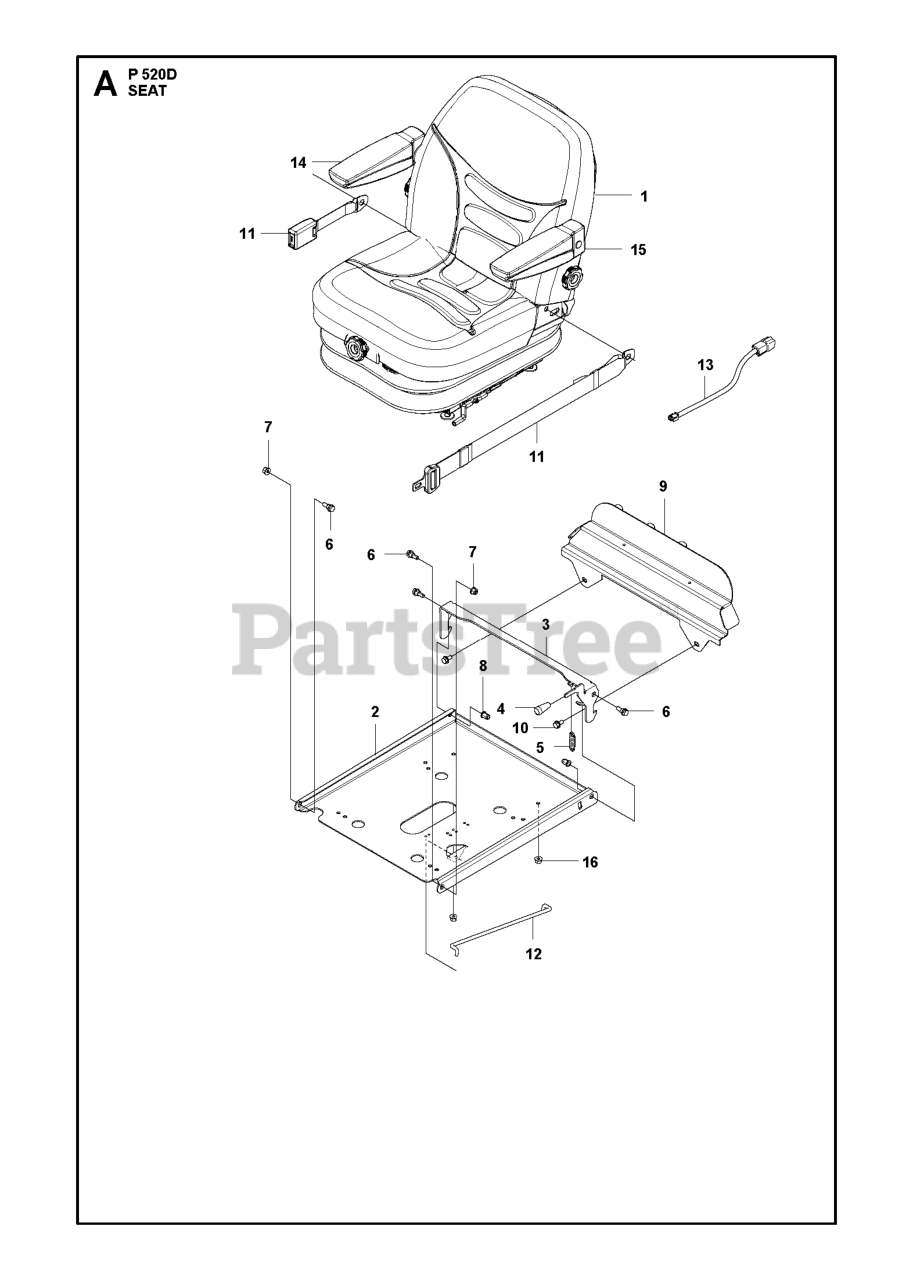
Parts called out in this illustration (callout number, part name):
5	DRAW SPRING L=50
7	NUT FLANGE
16	5/16-18 NYLOC FLANGE NUT
